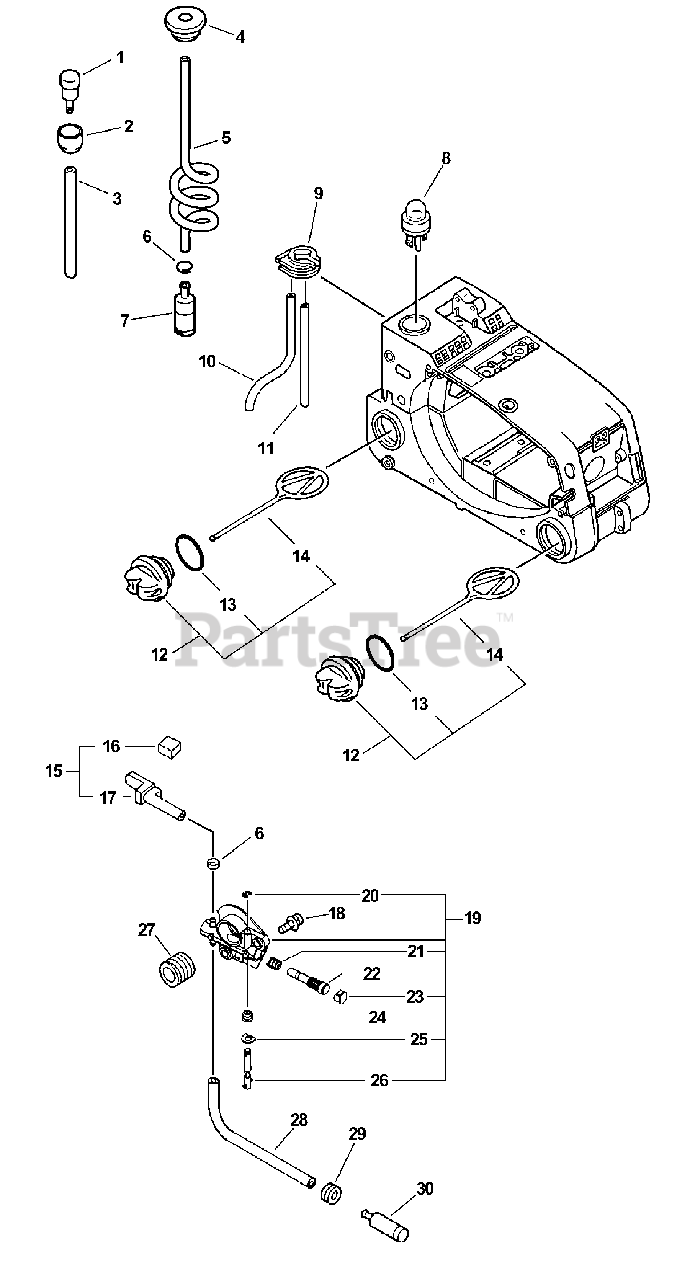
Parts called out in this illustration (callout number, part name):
1	VENT, FUEL TANK
2	HOLDER, VENT
3	PIPE - 3X5X150 -- BLACK
4	GROMMET
5	PIPE, FUEL - SPIRAL
6	CLIP - 6.5
7	FILTER, FUEL
8	PUMP, PURGE
10	PIPE - 2X4X42 -- CLEAR
11	PIPE - 3X5X70 -- BLACK
12	CAP ASSY - ORANGE
13	O-RING - 25
14	CONNECTOR, CAP
15	OIL PIPE KIT
16	PAD, FOAM
17	PIPE - OIL
18	SCREW - 5X12
19	AUTO-OILER ASSY
20	RING, RETAINING
21	SPRING, PLUNGER
22	PLUNGER ASSY
23	CAP, OIL PUMP
26	NEEDLE, ADJUST
27	GEAR - WORM
28	PIPE - 3X6X115 -- BLACK
29	GROMMET
30	FILTER, OIL
